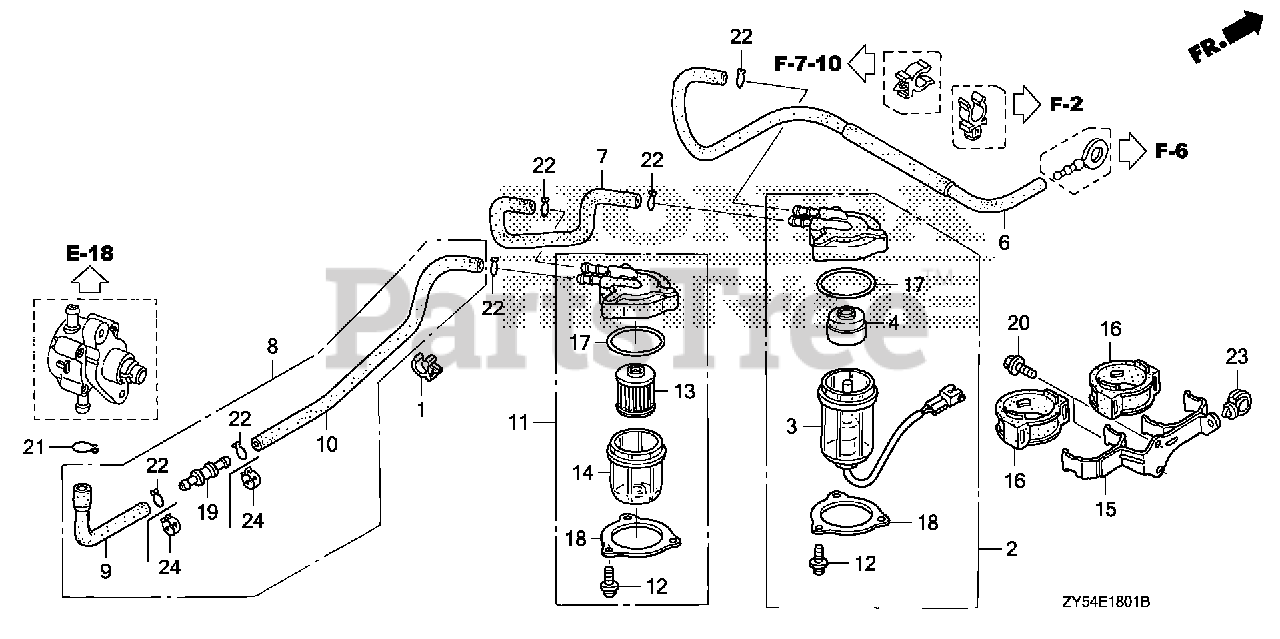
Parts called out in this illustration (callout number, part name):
1	CLIP, TUBE
2	SEPARATOR ASSY., WATER
3	CUP SET, WATER SEPARATOR
4	BUFFER, PLATE
6	TUBE A, FUEL (FRAME NO.)
6	TUBE A, FUEL (FKM)
7	TUBE C, FUEL
8	TUBE ASSY. D, FUEL
9	TUBE D, FUEL
10	TUBE E, FUEL
11	FILTER, FUEL
12	SCREW, PAN (5X12)
13	FILTER, FUEL
14	CUP, FUEL STRAINER
15	STAY, FUEL STRAINER
16	SUSPENSION, STRAINER
19	JOINT, FUEL TUBE
20	BOLT, FLANGE (6X14)
21	CLIP, TUBE (B1 14.5)
22	CLIP, TUBE (B12)
23	CLIP, WIRE HARNESS (25MM)
24	CLAMP, TUBE (D12)
